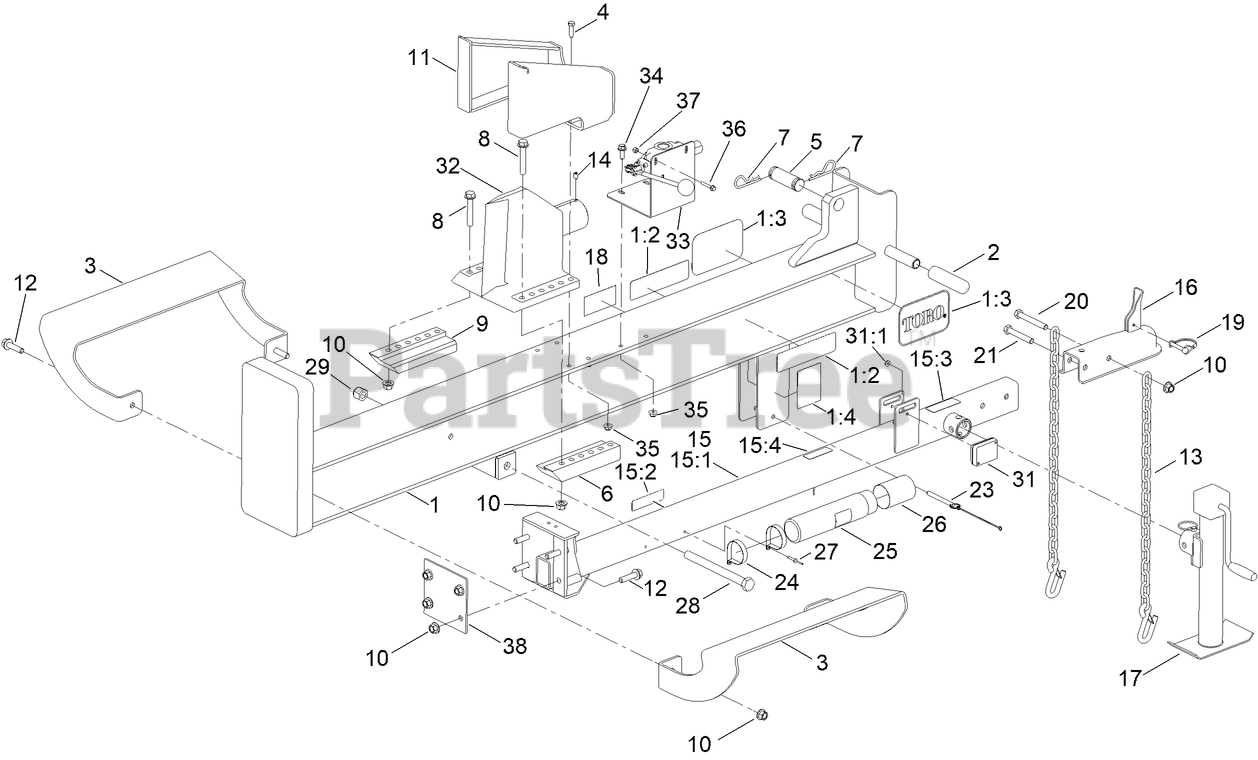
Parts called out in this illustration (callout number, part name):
1	BEAM ASM
1:3	DECAL
1:4	DECAL-WARNING, PIN
2	GRIP-HANDLE
3	PLATE-CATCH
4	SCREW-HH
5	PIN-PIVOT
6	BAR-SLIDE, LH
7	PIN-HAIR
8	SCREW-HF
9	BAR-SLIDE, RH
10	NUT-LOCK
11	DISLODGER BRACKET ASM
12	SCREW-HF
13	CHAIN-SAFETY, TRAILER
14	SCREW-SET
15	DECAL ASM-TUBE
15:1	TONGUE ASM [RED]
15:2	DECAL-ARRESTOR, SPARK
15:3	DECAL-CAUTION
15:4	DECAL-WARNING, PINCH POINT
16	RECEIVER-BALL HITCH
18	DECAL-TOOL, THD
19	PIN-LOCK
20	SCREW-HH
21	SCREW-HH
24	CLAMP-R
25	TUBE-MANUAL
26	CAP-HOUSING
27	RIVET-BLIND
28	BOLT-HH
29	NUT-LOCK, NI
31	LAMP-MARKER, FRONT SIDE
31:1	NUT-KEPS
32	WEDGE [BLACK]
33	BRACKET-VALVE
34	SCREW-HHF
35	NUT-HF, NI
36	SCREW-HHF
37	NUT-LOCK, NI
38	PLATE - BACKING
